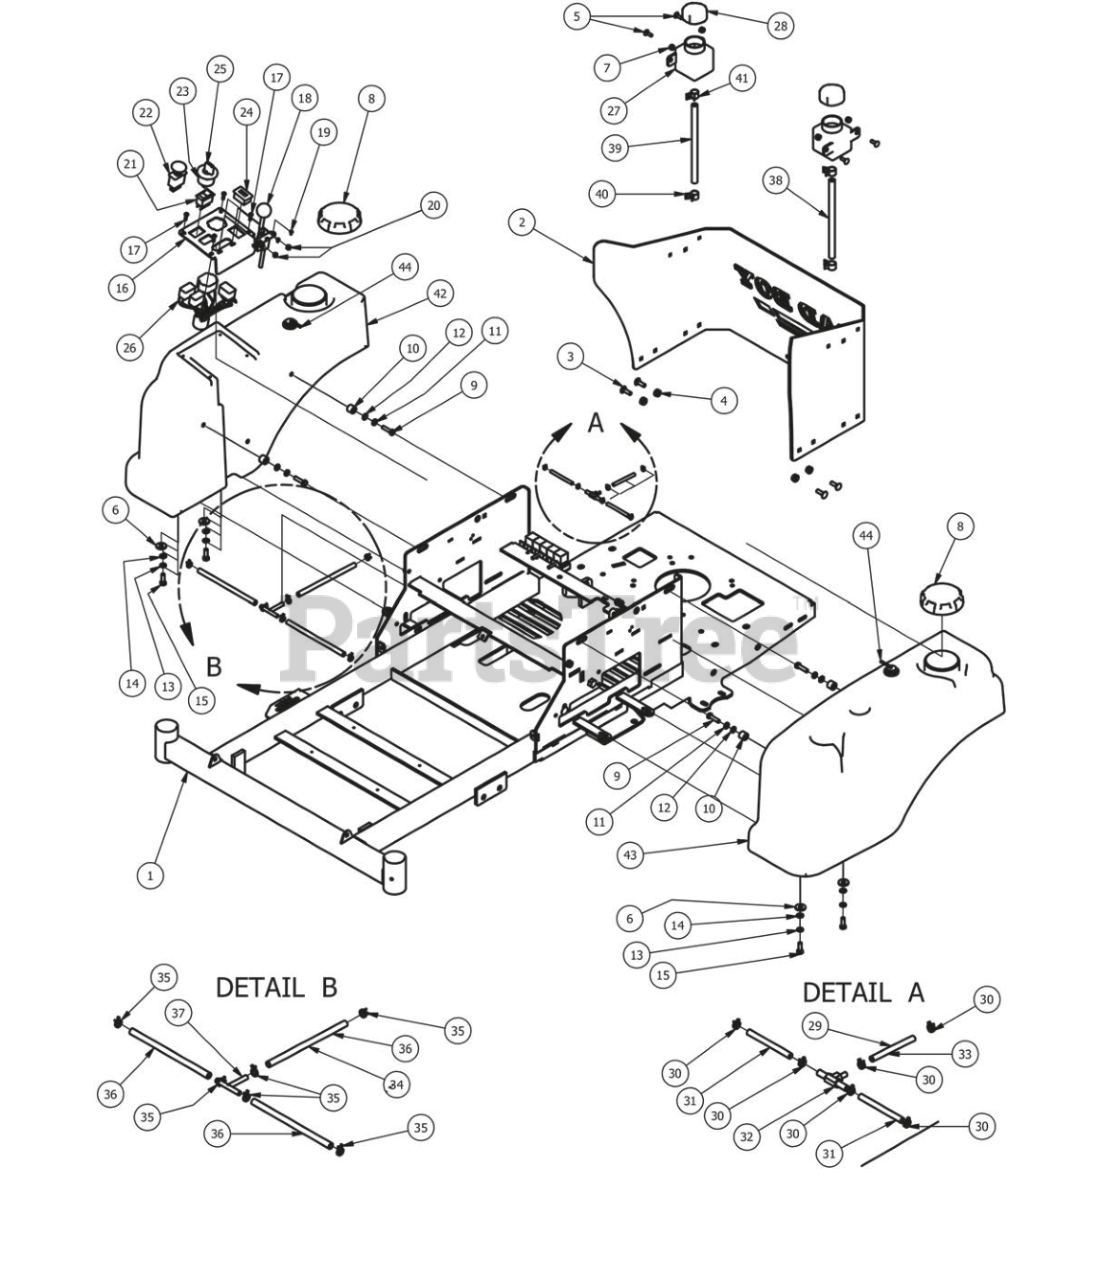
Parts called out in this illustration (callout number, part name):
1	ZT/CZT Frame 2013 Models
2	2013 ZT/CZT Rear Cover 27KO/26KA
3	5/16" x 1" Carriage Bolt
4	5/16-18 Nylon Flange Nut
5	1/4" x 3/4" Carriage Bolt
6	.360 ID Plastic Washer
7	1/4" Nylock Nut
9	5/16 x 1 1/4 Hex Bolt
10	.380x.735x.470 Nylon Spacer
11	5/16" Lock Washer
12	1/4" Flat Washer
13	5/16" Lock Washer
14	1/4" Flat Washer
15	5/16" x 1" Bolt
16	2013 ZT/CZT Control Panel
17	10-32 x 3/8" Button Socket Head Bolt
18	Throttle Lever Assembly
19	10-24 X 5/8 BS C/S 18-8 SS
20	10-24 Nylon Insert Locknut
21	Rocker Deck Lift Switch - 2011
22	PTO Engager
23	Ignition Switch
24	Tachometer
25	Ignition Key
26	Harness-ZT Only-2008 and up
27	350ml Expansion Tank-CZT
28	Hydraulic Tank Cap
29	2013 ZT Air Hose Assembly
30	3/16 vinyl clamp
31	3/16 vinyl tubing
32	Brass fuel line T
33	3/16 vinyl tubing
34	2013 ZT Fuel Line Assembly
35	1/4 fuel clamp
36	1/4" fuel line hose
37	fuel line T
38	2013 ZT Hydraulic Hose Assembly
39	3/8 clear hose price per foot
40	1/2 Hose Clamp
41	3/8 hose clamp
42	2013 ZT Fuel Tank- Right
43	2013 ZT Fuel Tank- Left
44	Rollover Valve-White
